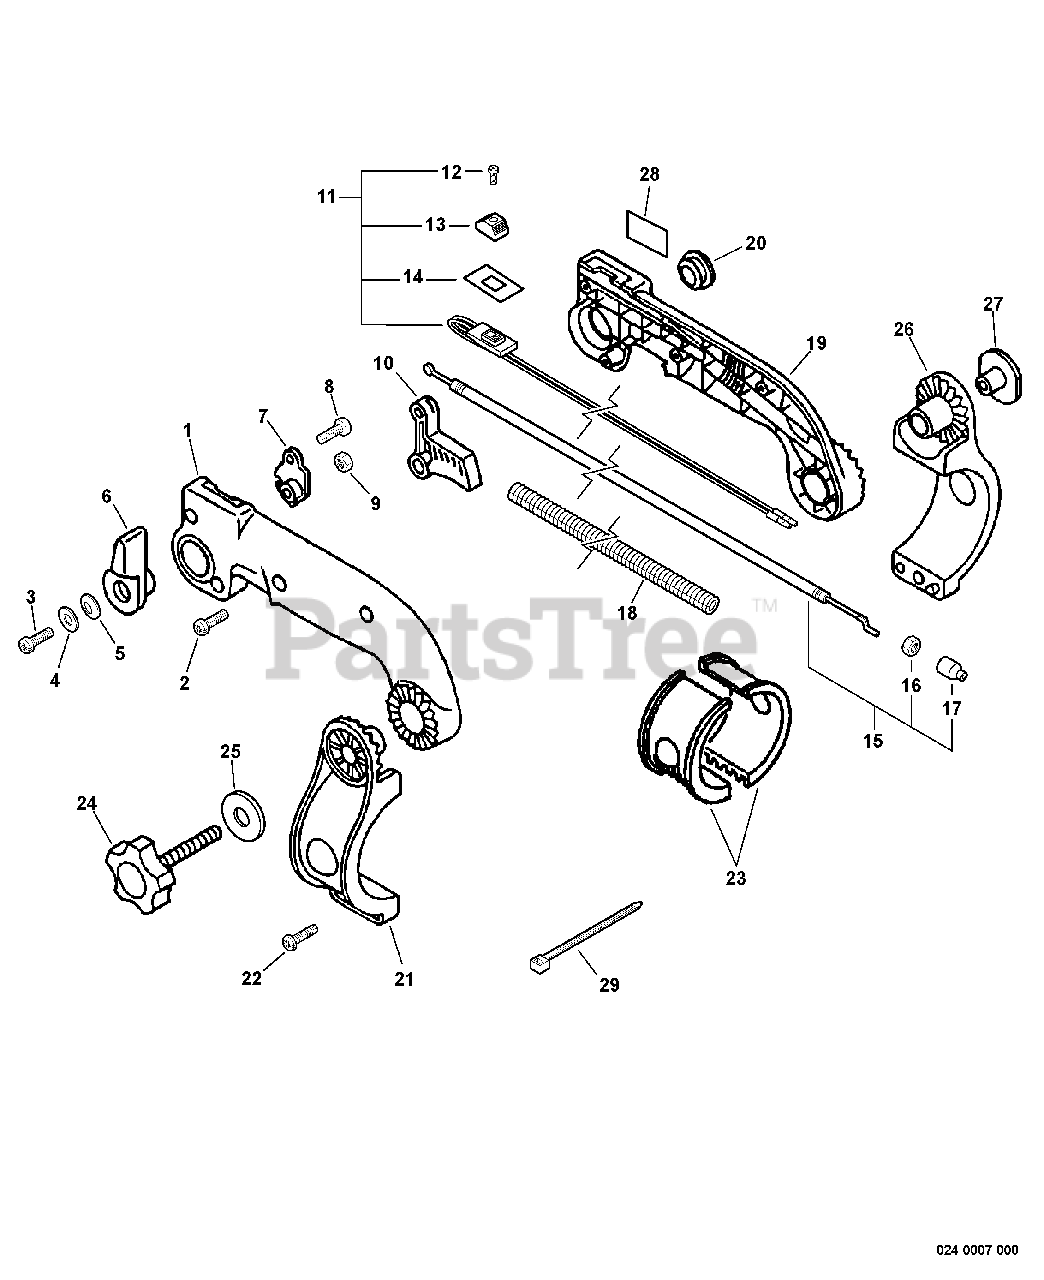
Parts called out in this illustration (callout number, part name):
1	CONTROL HANDLE - LEFT
2	SCREW 4×22
3	SCREW 6×20
4	WASHER, SPRING 6
5	WASHER 6.5×13×1
6	CONTROL, THROTTLE
7	BRACKET, THROTTLE
8	SCREW 4×10
9	NUT, HEX M6
10	TRIGGER, THROTTLE
11	SWITCH, ON-OFF
12	SCREW 3×10
13	KNOB, SWITCH - ORANGE
14	LABEL, SWITCH
15	CABLE, THROTTLE
16	NUT, HEX M6
17	CAP, DUST
18	TUBE, FLEXIBLE 7×790
19	CONTROL HANDLE - RIGHT
21	BRACKET, HANDLE - LEFT
22	SCREW, TAPPING 5×20
24	KNOB, SCREW
26	BRACKET, HANDLE - RIGHT
28	LABEL, ON-OFF
29	STRAP, TIE - LARGE
